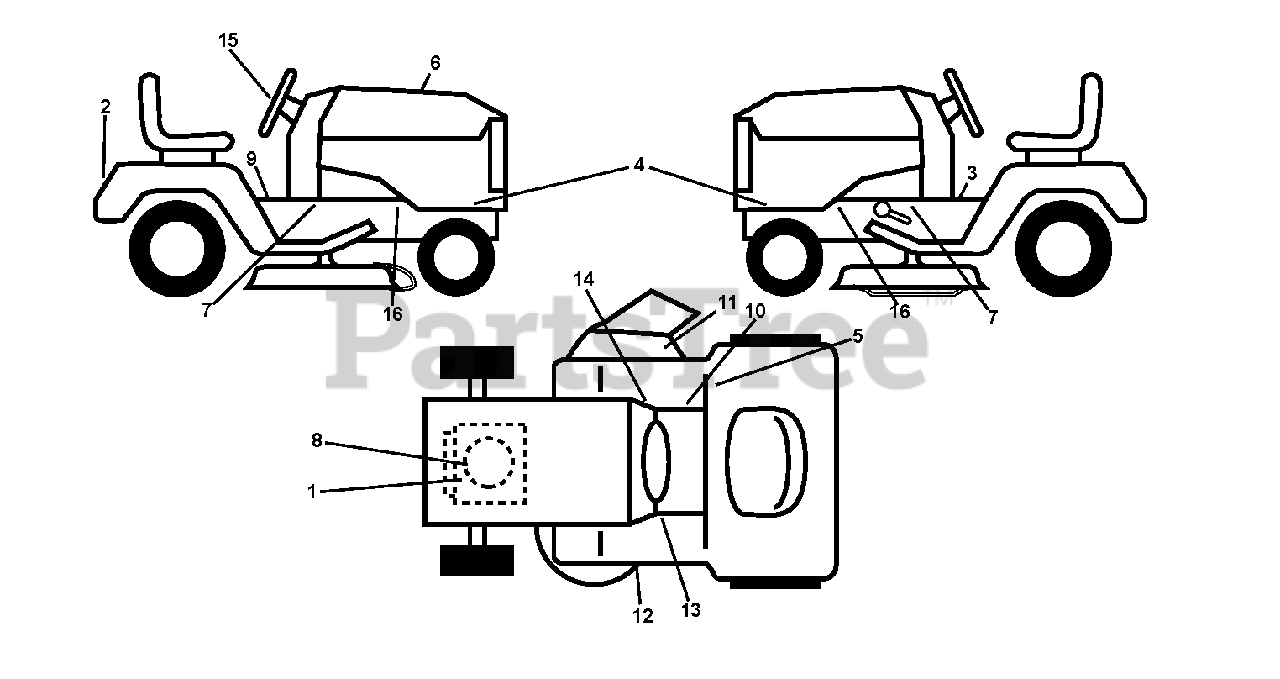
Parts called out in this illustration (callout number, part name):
9	DECAL BTRY SYMBOLS
11	DECAL.WARN.DFLECT/CTFINGR.SRD
14	DECAL PARK BRAKE
